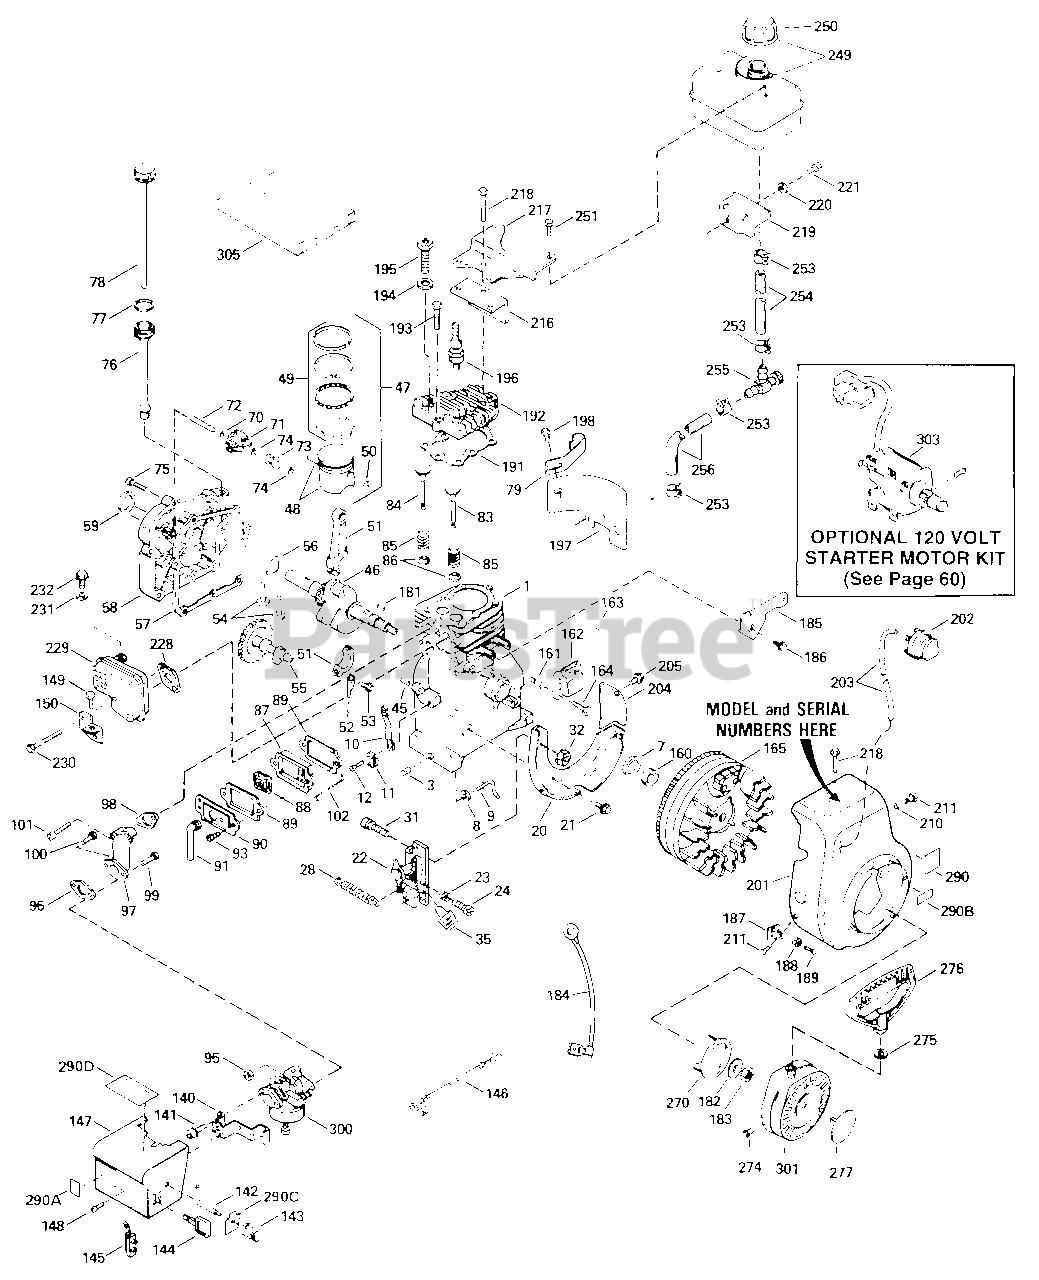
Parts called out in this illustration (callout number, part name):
1	Cylinder Ass'y.
3	Plug, Pipe, 1/4-18
7	Seal, Oil
8	Washer, Flat
9	Rod, Governor
10	Lever, Governor
11	Clamp, Governor Lever
12	Screw, Hex Washer Hd., 8-32 x 5/16
20	Baffle, Blower Housing
21	Screw, Hex Washer Hd. Durlok, 1/4 -20 x 5/8
22	Control Ass'y., Bracket
23	Spring, Compression
24	Screw, Fil. Hd., 5-40 x 7/16
28	Spring, Extension
31	Screw, Fil. Hd. Sems, 8-32 x 1/2
32	Nut, Lock, 8-32
35	Knob, Speed Control
45	Pin, Dowel
46	Crankshaft Ass'y.
47	Piston, Pin & Ring Ass'y. (Std.)
48	Piston & Pin Ass'y. (Std.)
49	Ring Set, Piston (Std.)
50	Ring, Piston Pin Retaining
51	Rod Ass'y., Connecting
52	Dipper, Oil
53	Screw, Connecting Rod
54	Lifter, Valve
55	Camshaft (Compression Release)
56	Washer, Thrust
57	Gasket, Cylinder Cover
58	Cover, Cylinder
59	Seal, Oil
70	Washer, Flat
71	Gear, Governor
72	Shaft, Mechanical Governor
73	Spool, Governor
74	Ring, Retaining
75	Screw, Hex Hd. Sems, 1/4-20 X 1 1/4
76	Tube Ass'y., Oil Fill
79	Clip, Oil Fill
83	Valve, Exhaust (Std.)
83	Valve, Exhaust (1/32" Oversize)
84	Valve, Intake (Std.)
84	Valve, Intake (1/32" Oversize)
85	Spring, Valve
86	Cap, Valve Spring
87	Body, Valve Cover
88	Element, Valve Body
89	Gasket, Valve Cover
90	Cover, Breather
91	Tube, Breather
93	Screw, Fil. Hd. Sems, 10-24 x 1/2
95	Nut & Lock Washer Ass'y., 1/4-28
96	Gasket, Carburetor
97	Pipe, Intake
98	Gasket, Intake
99	Screw, Hex Hd., 1/4-28 x 7/8
100	Screw, Hex Hd., 1/4-28 x 1-11/16
101	Screw, Fil. Hd. Sems, 1/4-20 x 1-19/32
102	Link, Governor to Throttle
140	Bracket, Choke
141	Screw, Fil. Hd. Sems, 10-32 x 1/2
142	Rod, Choke
143	Knob, Choke Control
144	Key, Ignition
145	Terminal Ass'y.
146	Wire, Ground
147	Cover, Carburetor
148	Screw, Pan Hd. Sems, 8-32 x 5/16
149	Screw, Hex Hd. Sems, Taptite,10-24 x 3/8
150	Bracket, Carburetor Cover
160	Spacer, Flywheel Key
161	Stud, Solid State Mounting
162	Solid State Ass'y.
163	Cover, Spark Plug
164	Screw, Hex Hd. Sems, 10-24 x 1
165	Flywheel (w/Ring Gear)
181	Key, Flywheel
182	Washer, Belleville
183	Nut, Flywheel
184	Wire, Ground
185	Bracket, Hold Down
186	Screw, Hex Washer Hd. Self-Tap Sems, 1/4-15 x 7/8
187	Bracket, Grommet Mounting
188	Grommet, Plastic
189	Screw, Pan Hd. Taptite, 8-32 x 3/8
191	Gasket, Cylinder Head
192	Head, Cylinder
193	Screw, Hex Flange Hd., 5/16-18 X 1 1/2
194	Washer, Flat
195	Screw, Special Hex Hd., 5/16-18 X 1 1/2
196	Plug, Spark
197	Extension, Blower Housing
198	Screw, Fil. Hd. Sems, 10-24 x 1/2
201	Housing, Blower
202	Primer Ass'y.
203	Line, Primer
204	Extension, Baffle
205	Screw, Hex Washer Hd. Shake-proof Self-Drilling, 8-18 x 7/16
210	Washer, Flat
211	Screw, Hex Hd. Sems,1/4-28 x 7/16
216	Baffle, Heat
217	Plate, Fuel Tank
218	Screw, Hex Flange Hd., 5/16-18 x 2
219	Bracket, Fuel Tank Mounting
220	Washer, Flat
221	Screw, Hex Hd., w/Belleville Washer, 1/4-20 x 11/16
228	Gasket, Exhaust
229	Muffler
230	Screw, Fil. Hd. Sems, 1/4-20 x 2 1/2
231	Washer, Flat
232	Screw, Hex Washer Hd. Sems, 1/4 - 20 x 1/2
249	Tank Ass'y., Fuel
250	Cap, Fuel Tank
251	Screw, Hex Washer Hd. Self-Tap Sems, 1/4-15 x 7/8
253	Clamp, Fuel Line
254	Line, Fuel
255	Valve, Shut-Off
256	Line, Fuel
270	Cup, Starter
274	Washer, Flat
275	Washer, Flat
276	Handle, Starter
277	Plug, Starter
290	Decal, Name
290A	Decal, Instruction
290B	Decal, Primer
290C	Decal, Choke
290D	Decal, Warning
300	Carburetor
301	Starter, Rewind
303	Electric Starter Kit (Optional)
305	Gasket Set
